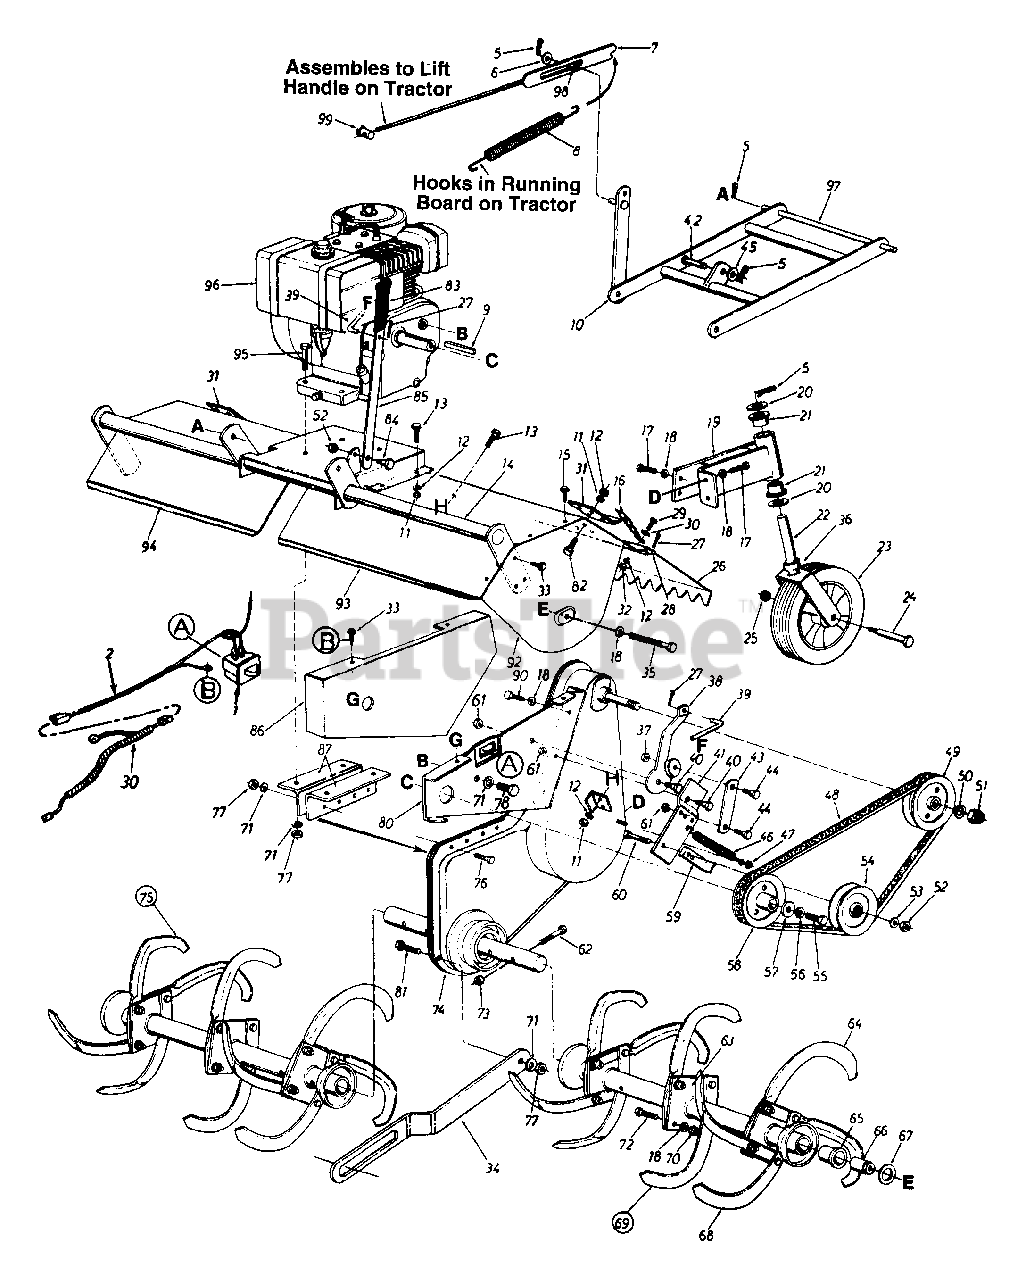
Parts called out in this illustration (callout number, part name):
1	Safety Switch
2	Wire Harness
3	Adapter Harness
5	Internal Cotter Pin
6	Fl-Wash. 1/2" I.D. x .93" O.D.
9	Sq. Key 1/4" x 1/4" x 2.00" Lg.
12	L-Wash. 1/4" I.D.
13	Hex Bolt 1/4-28 x .62" Lg.
16	#2 Dog Chain x 20" Lg.
17	Hex Wash. Hd. Self-Tap Scr. 3/8-24 x .75" Lg.
18	L-Wash. 3/8" I.D.
19	Swivel Wheel Support
20	Fl-Wash. 3/4" I.D. x 1.50" O.D.
21	Flange Bearing 3/4" I.D. x 1.00" O.D.
22	Swivel Wheel Caster
23	Wheel Assembly 10.0 x 2.75
24	Shoulder Bolt .623" I.D. x 3.62" Lg.
25	Hex Cent. L-Nut 7/16-14 Thd.
28	L.H. Flap Rod
28	R.H. Flap Rod
29	Hex Bolt 1/4-20 x .62" Lg.
30	Fl-Wash. 1/4" I.D.
33	Hex Wash. Hd. Self-Tap Scr. 1/4" x .62" Lg.
34	Stabilizer Link
35	Hex Bolt 3/8-16 x 1.25" Lg.
36	Spacer .752" I.D. x 1.25" O.D.
37	Hex Cent. L-Nut 5/16-18 Thd.
40	Shoulder Bolt 7/16" Dia. x 1.75"
45	Fl-Wash. .50" 1.0. x 1.0" O.D. x .06
46	Extension Spring .62" O.D. x 6.12" Lg.
47	Hex Crown Nut 3/8-24 Thd.
48	V-Belt
49	1/2" "V"-Pulley 4.75" O.D. x .625" Bore
50	L-Wash. 5/8" I.D.
51	Hex Ins. L-Nut 5/18-16 Thd.
52	Hex Cent. L-Nut 3/8-16 Thd.
53	Fl-Wash. 3/8" I.D.
54	Idler Pulley 4.0" O.D.
55	Hex Bolt 7/16-20 x 1" Lg.
56	L-Wash. 7/16" I.D.
57	Fl-Wash. 7/16" I.D. x 1.38"
58	1/2" "V"-Pulley .475" O.D. x 1.00" Bore
61	Hex Cent. L-Nut 5/16-18 Thd.
62	Hex Bolt 7/16-14 x 2.00" Lg.
65	Flange Bearing 1.00" I.D.
66	Spacer
67	Thrust Wash. 1/2" I.D. x 1.55"
68	Tine - R.H.
69	Tine Assembly Comp. - L.H.
70	Hex Nut 3/8-24 Thd.
71	L-Wash. 5/16" I.D.
72	Hex Bolt 3/8-24 x 1.5" Lg.
73	Hex Cent. L-Nut 7/16-14 Thd.
77	Hex Nut 5/16-18 Thd.
78	Hex Bolt 5/16-24 x .62"
80	Clutch Support Bracket
81	Shld. Bolt .435" Dia. x .265" 5/16-18 Thd.
82	Hex Bolt 1/4-28 x .75" Lg.
83	Plastic Grip
84	Shoulder Bolt .498" Dia. x .212" Lg.
87	Engine Mounting Bracket
90	Hex Bolt 3/8-16 x .62" Lg.
92	L.H. - Side Plate
96	8 H.P. Engine
97	Hitch Rod
98	Push Bar Sleeve .503" I.D. x .624" O.D.
99	Ferrule
